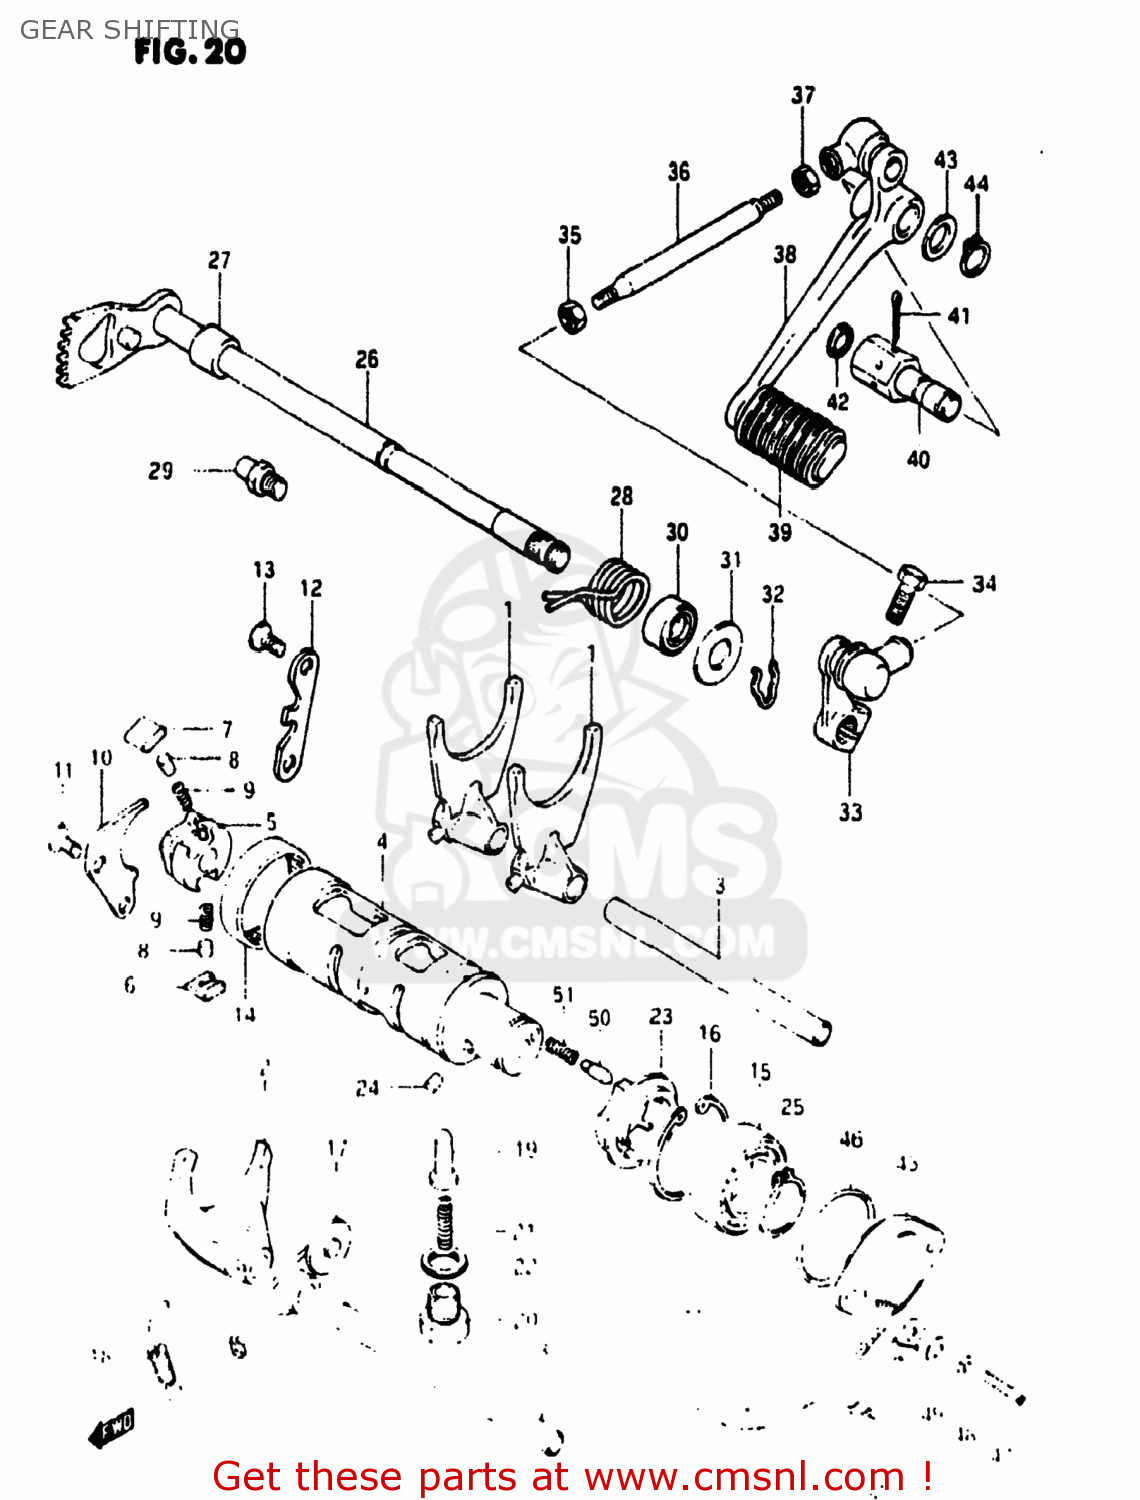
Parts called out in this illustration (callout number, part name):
1	FORK,GEAR SHIFT NO.1
2	FORK,GEAR SHIFT NO.2
3	SHAFT,GEAR SHIFT FORK
4	CAM,GEAR SHIFT
5	GEAR,GEARSHIFT CAM DRIVE
6	PAWL,GEAR SHIFT NO.1
7	PAWL,GEAR SHIFT NO.2
8	PIN(5X8)
9	SPRING
10	LIFTER,GEAR SHIFT POLE
11	SCREW
12	GUIDE,GEAR SHIFT CAM
13	SCREW
14	BEARING(43X49X12)
15	BALL BEARING
16	CIRCLIP,42MM
17	STOPPER,GEAR SHIFTING CAM
18	SPRING
19	STOPPER,GEAR SHIFT CAM NO.2
20	HOLDER,GEAR SHIFT CAM STOP SPR
21	SPRING
22	GASKET(14X19.2X2) (NAS)
23	PLATE,GEAR SHIFT CAM STOPPER
24	PIN 4X6
25	CIRCLIP,25MM
26	SHAFT,GEAR SHIFT
27	SPACER(12X20X15.3)
28	SPRING
29	STOPPER,GEAR SHIFT CAM
30	OIL SEAL
31	WASHER (12.5X27X1.6)
32	SPRING,RETAINER
33	ARM,GEAR SHIFT LINK
34	BOLT
35	NUT 6MM
36	ROD,GEAR SHIFT LINK
37	NUT
38	LEVER ASSEMBLY,GEAR SHIFTING
39	RUBBER,PEDAL
40	SHAFT,GEAR SHIFT LEVER
41	COTTER PIN
42	WASHER
43	WASHER(12.5X20X1)
44	CIRCLIP
45	BASE ASSEMBLY,NEUTRAL SWITCH TERMINAL
46	O RING(D:2.4,ID:36.5)
47	SCREW(5X14)
48	LOCK WASHER
49	WASHER
50	PIN(5X15.5)
51	SPRING
52	CLAMP L:35
